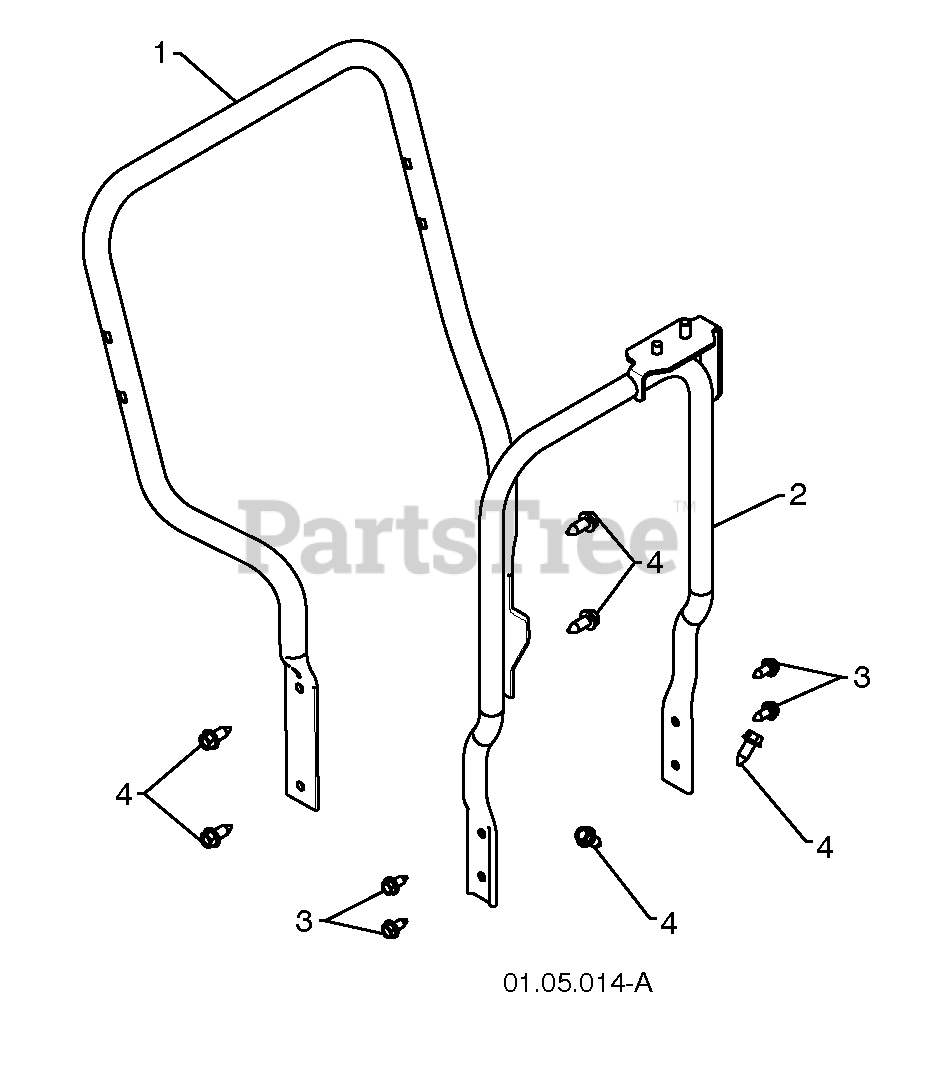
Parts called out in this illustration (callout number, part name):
1	LOWER TUBE GRAY
2	PIVOT SUPPORT
3	BOLT 5/16-18 X .750
4	SCREW 3/8-16 X 1.00
